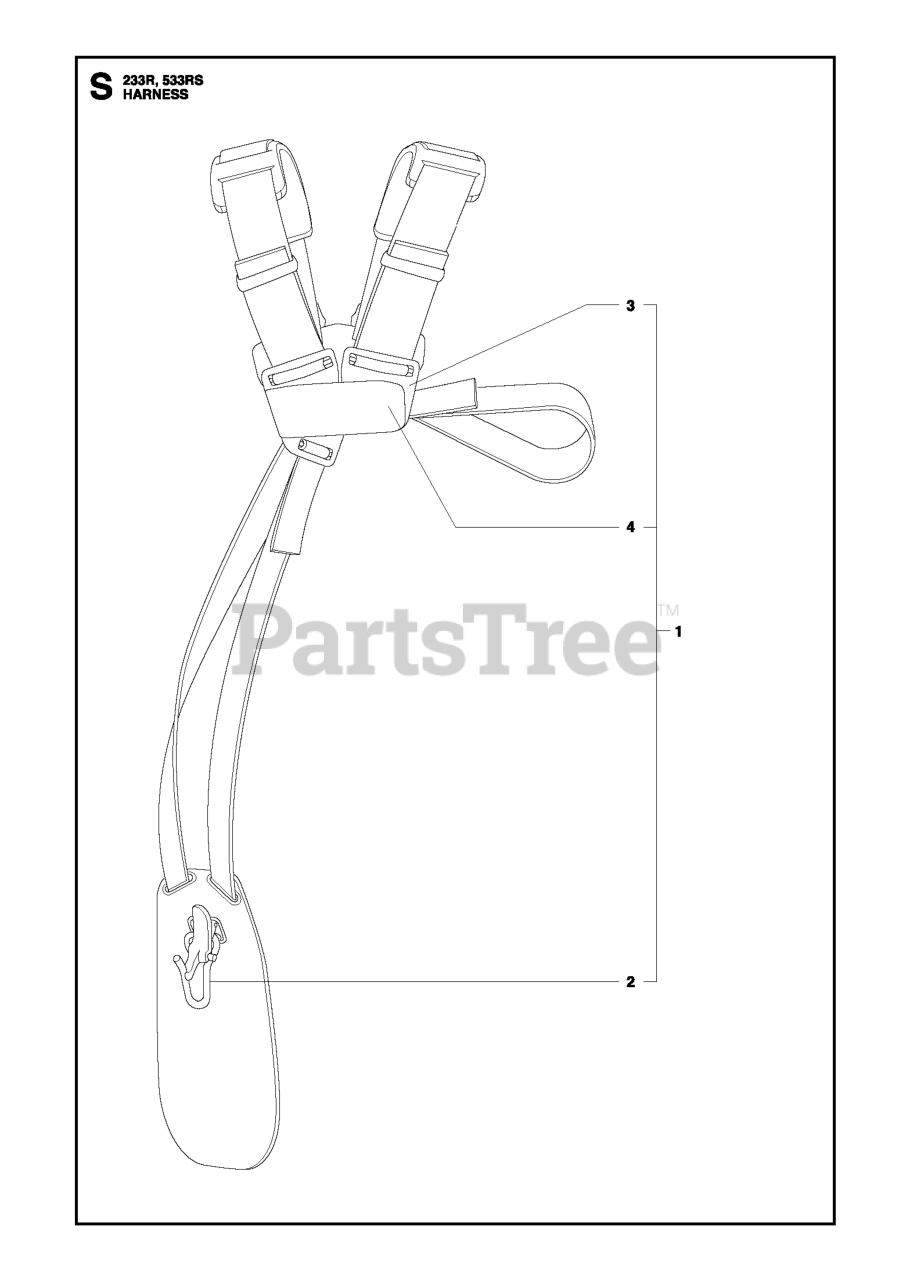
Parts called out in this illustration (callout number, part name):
1	Harness-w/o warning
1	HARNESS DUO
2	HOOK, CPL.
3	BUCKLE
4	STRAP
